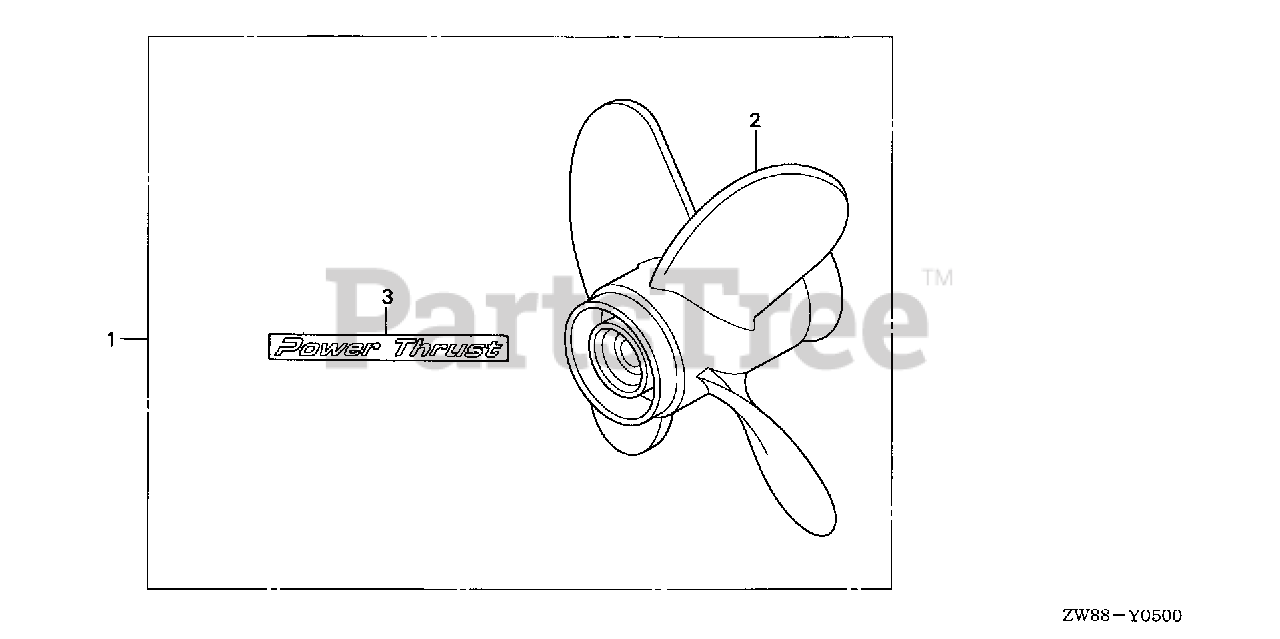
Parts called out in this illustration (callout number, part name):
1	PROPELLER KIT, POWER THRUST
1	PROPELLER KIT, POWER THRUST *NH283* (STIN GRAY)
2	PROPELLER, FOUR BLADES (10X6-1/2 HT) *NH283* (STIN GRAY)
3	MARK, POWER THRUST
